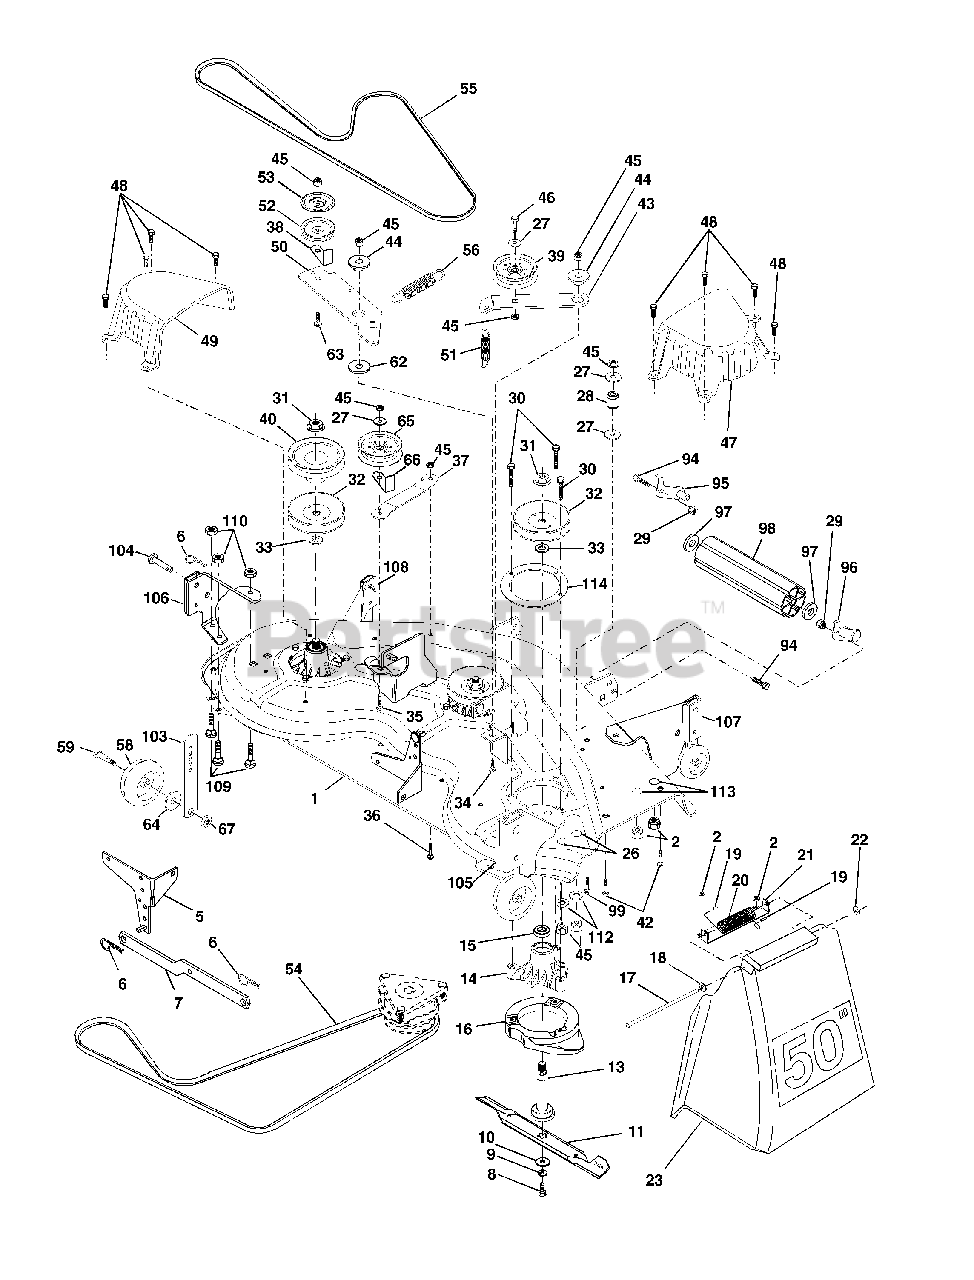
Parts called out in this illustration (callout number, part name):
1	Deck Asm., Mower 50"
2	Nut, Crownlock 5/16-18
5	Bracket Asm., Sway Bar
6	Retainer, Spring
7	Arm Suspension, Rear
8	Bolt 3/8-24 x 1.25 Gr. 8 Patched
9	Washer, Lock Hvy 3/8 Unplated
10	Washer, Hard Blade Mower Vented
11	Blade (3 Required)
13	Shaft Asm., W/Lower Brg
14	Housing, Mandrel 50" Vent
15	Bearing, Ball Mandrel
16	Stripper, Mower
17	Rod, Hinge
18	Washer 11/32 x 5/8 x 16 Ga.
19	Cap Sleeve
20	Spring, Torison Delector
21	Bracket, Deflector
23	Shield, Deflector Mower
26	Bolt Rd Hd Sht Sqnk
27	Washer 13/32 x 13/16 x 16 Ga.
28	Spacer, Spring Stop Idler
29	Nut, Lock Hex 5/16-18
30	Screw Thd Rolling Washer Head
31	Nut, Flg Top Lock
32	Pulley, Mandrel
33	Washer, Spacer Mower Vented
34	Bolt, Carriage 3/8-16 x 1-1/4
35	Bolt, Carriage 3/8-16 x 2
36	Bolt, Carriage 3/8-16 x 1 Gr. 5
37	Stiffener, Arm Idler
38	Keeper, Belt Idler
39	Pulley, Idler Flat
40	Pulley, Driven
42	Bolt, Carriage 5/16-18 Unc x 3/4
43	Arm, Idler Secondary
44	Spacer, Retainer
45	Nut, Crownlock 3/8-16 Unc
46	Bolt, Fin Hex 3/8-16 Unc x 1-3/4
47	Cover, Mandrel RH
48	Screw, Thd Roll 1/4-20 x 5/8
49	Cover, Mandrel LH
50	Arm, Idler Primary
51	Spring, Secondary
52	Pulley, Idler V Groove
53	Shield, Idler
54	V-Belt, Mower Primary
55	V-Belt, Mower Secondary
56	Spring, Primary
58	Wheel, Gauge
59	Bolt, Shoulder
62	Washer Hardened
63	Bolt Carriage 3/8-16 x 1-1/2
64	Washer 3/8 x 7/8 x 14 Ga.
65	Pulley Idler Flat Mower
66	Keeper, Belt Idler 50" Vent
67	Nut, Center Lock 3/8-16
94	Bolt H 5/16-18
95	Bracket, Asm. Noseroller LH
96	Bracket, Asm. Noseroller RH
97	Washer 17/32 x 7/8 x 16 Ga.
98	Roller, Nose
99	Bolt, Carriage 3/8-16 x 1-3/4 Gr. 5
103	Bar Adj. Gauge Wh.
104	Pin Head Rivot
105	Bracket Ga Wh Asm RH 50
106	Bracket Ga Wh Asm LH 50
107	Bracket Ga Wh Assy F RH 50
108	Bracket Ga Wh Assy F LH 50
109	Bolt Carraige 5/16- 18 x 5/8
110	Nut Crownlock 5/16-18
112	Washer 17/32 x 3/4 x 16 Ga.
113	Bolt Carriage 5/16-Unc 1/2
114	Reinforcement Mandrel Ring
